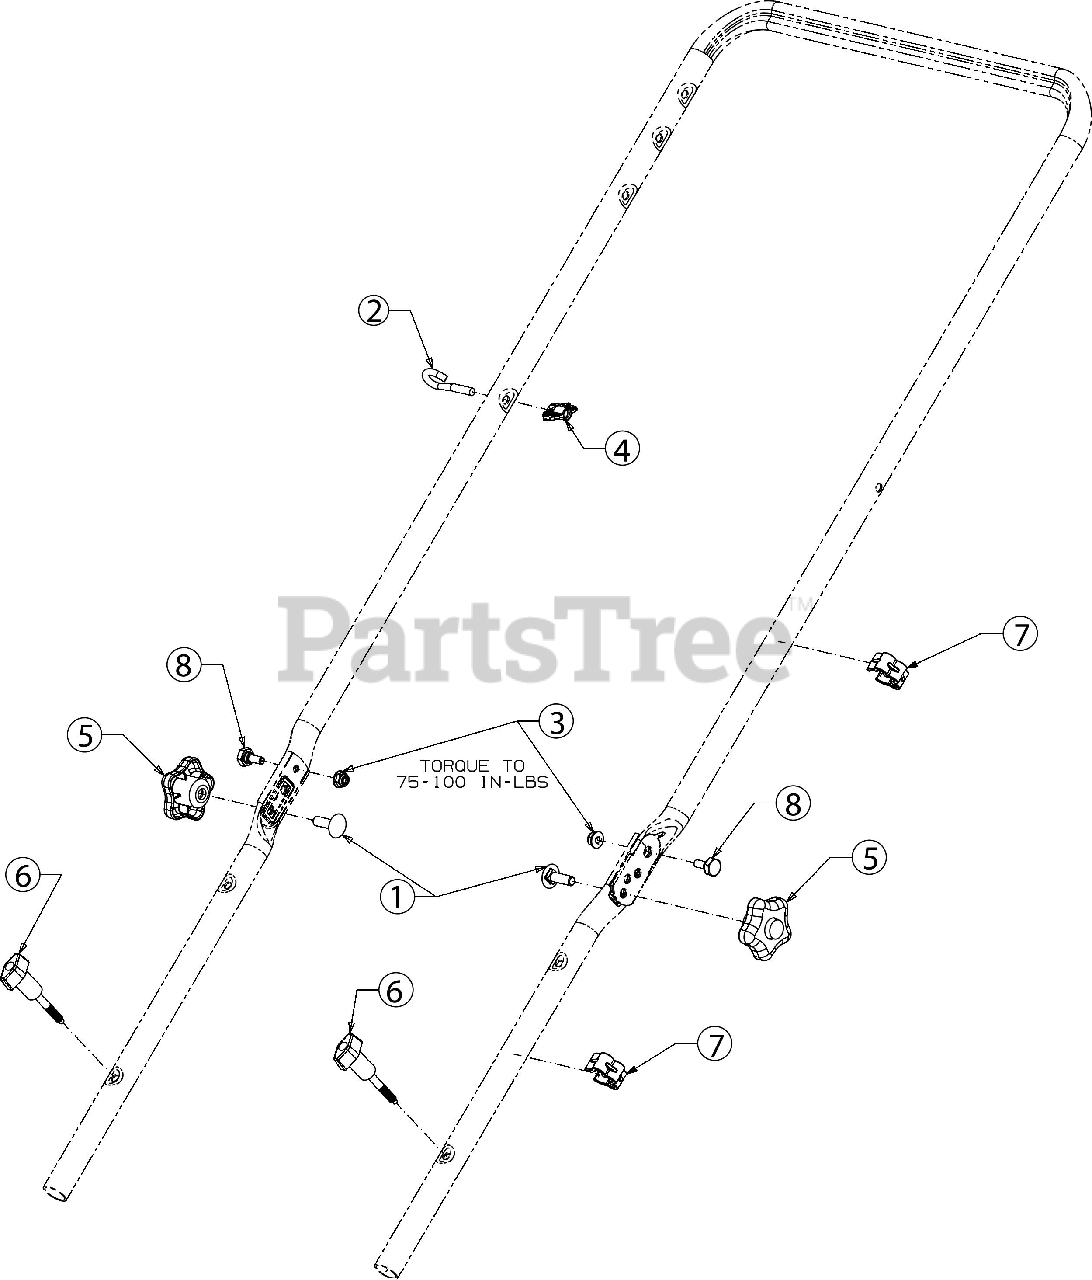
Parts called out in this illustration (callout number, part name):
1	SCREW 5/16-18 X 1.00 GR5
2	EYEBOLT 1/4-20
3	FLANGE LOCK NUT
4	HANDLE KNOB
5	STAR KNOB- YELLOW
6	WING KNOB 1/4-20
7	CONDUIT CLIP
8	SHOULDER SCREW
